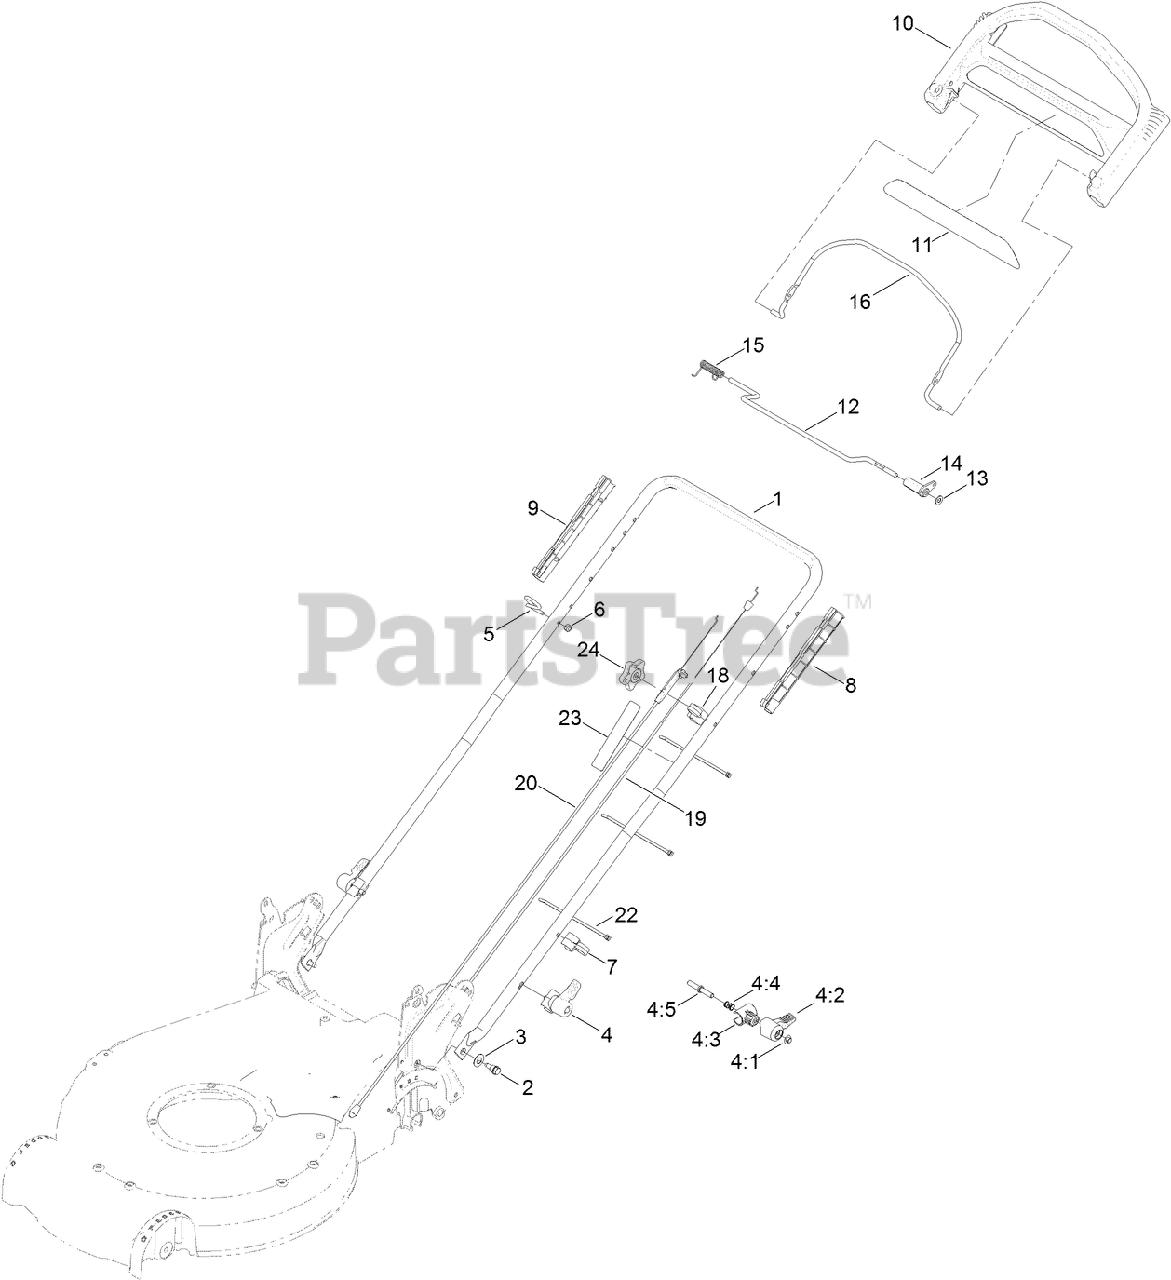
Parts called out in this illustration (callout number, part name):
2	BOLT-SHOULDER
3	WASHER-SPRING, CONICAL
4	QUICK RELEASE ASM
4:2	LEVER
4:3	ANCHOR-SPRING
4:4	SPRING-COMPRESSION
4:5	ROD-RELEASE
5	GUIDE-ROPE
6	NUT-LOCK, NI
7	GUIDE-CABLE
8	GUIDE-LH
9	GUIDE-RH
10	HANDLE-CONTROL
13	WASHER-PLAIN
14	LEVER-TRACTION
19	CABLE-TRACTION
20	CABLE-BRAKE
22	TIE-CABLE
24	KNOB-HANDLE, LOCKING
